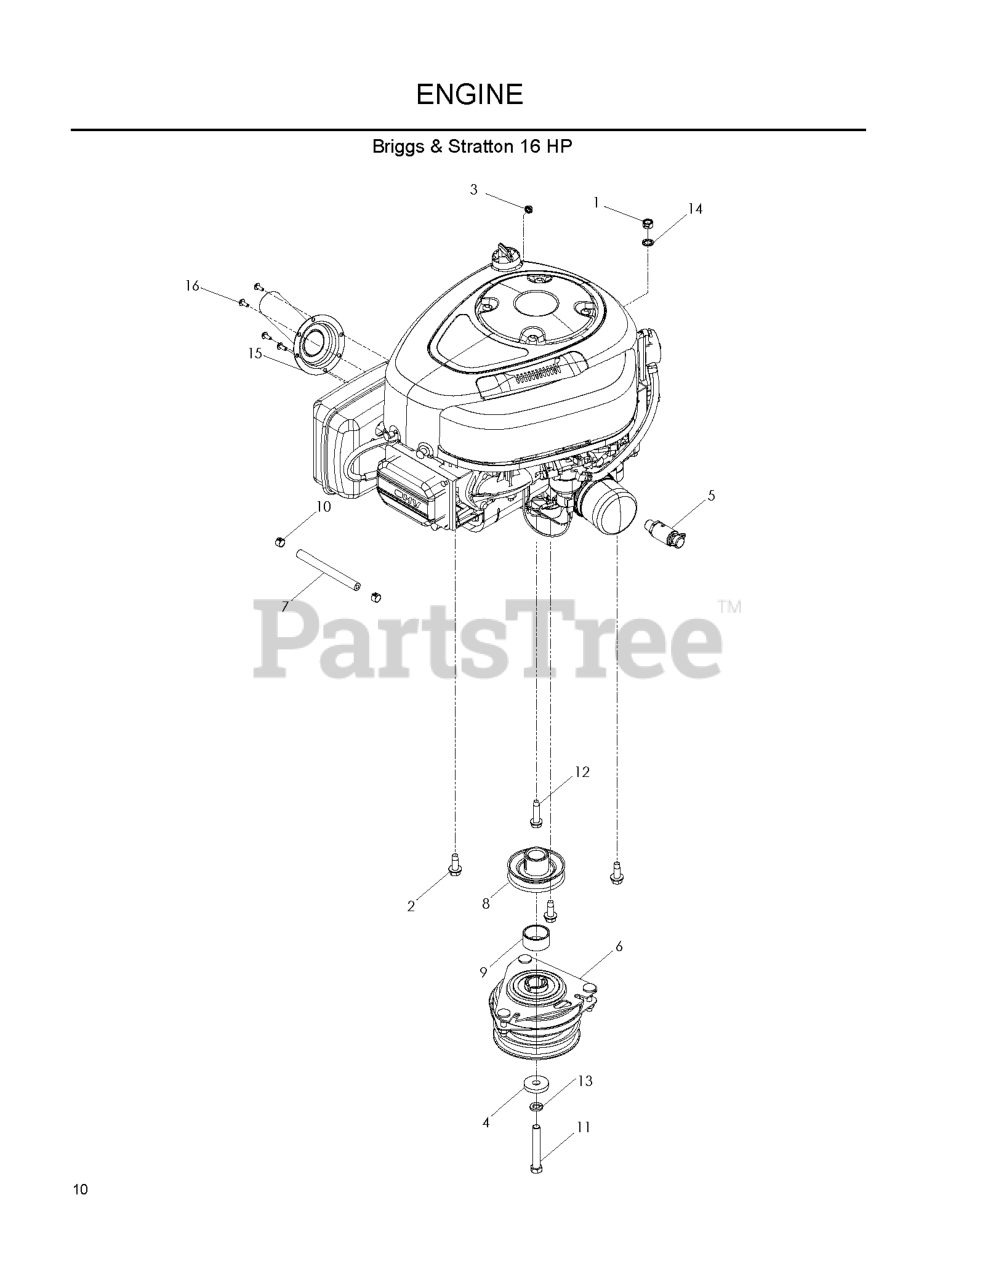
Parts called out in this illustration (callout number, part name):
1	NUT 3/8C CENTERBLOCK
2	BOLT 3/8-16 X 1.0
3	JAM NUT 1/4C (2 2 PW01)
4	CLUTCH, WASHER
5	OIL DRAIN FITTING
6	CLUTCH 90 FT/LB OGURA
7	FUEL LINE 5"
8	PULLEY, ENGINE
9	SPACER, ENGINE - PULLEY
10	HOSE CLAMP
11	HEX SCREW 7/16-20 X 3
12	BOLT 3/8-16 X 1 1/2 ZINC CLEAR
13	WASHER 7/16 LOCK
14	WASHER, 3/8 ITLW ZN
15	MUFFLER EXT.(PAINTED)
16	SCREW, TAP #10-16 X 1/2
